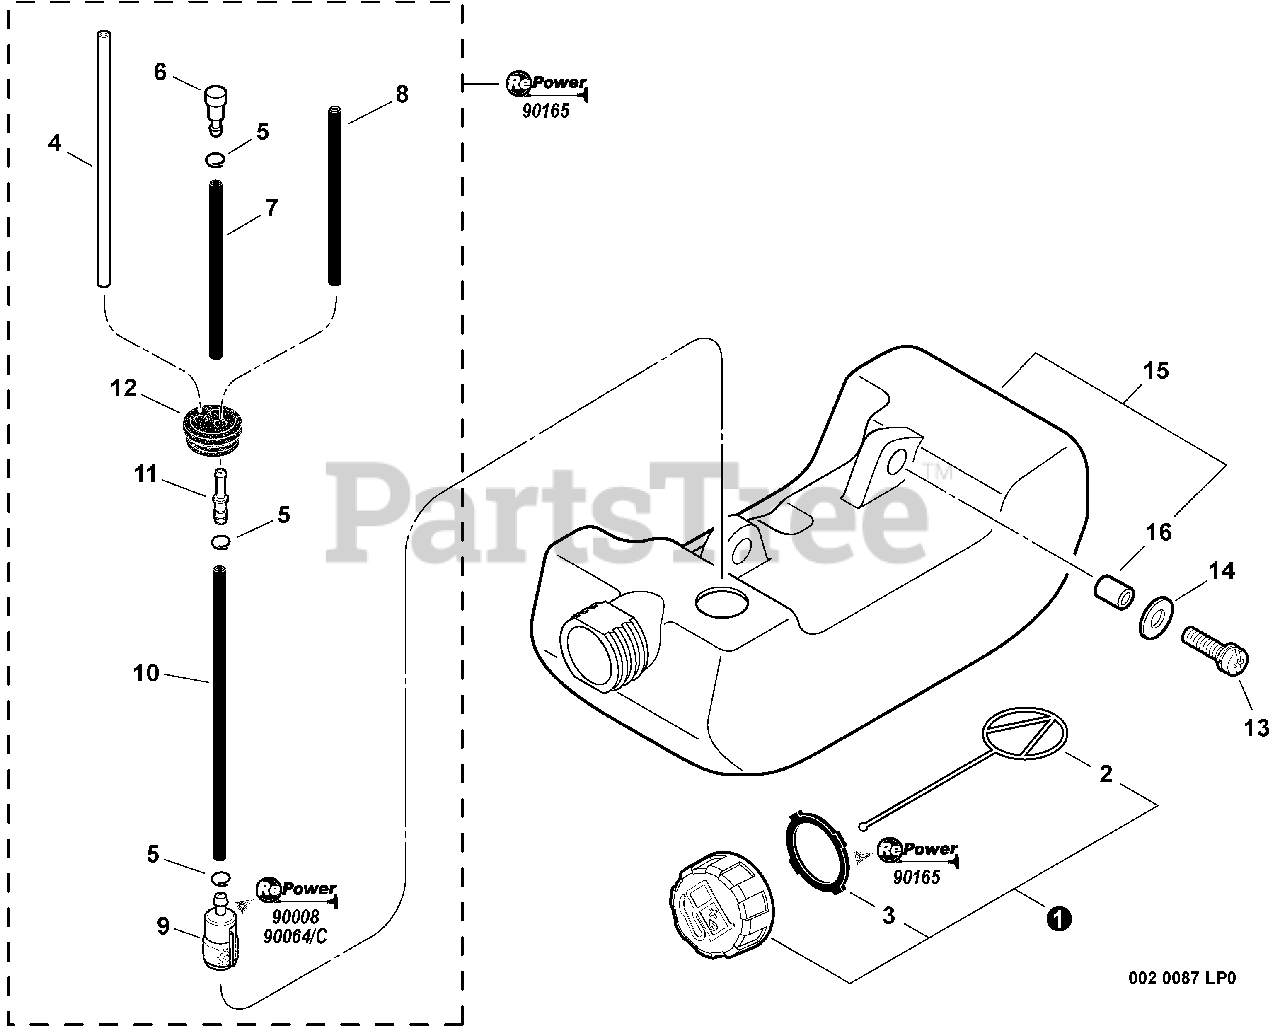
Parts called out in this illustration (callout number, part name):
1	CAP ASSY - ORANGE
2	CONNECTOR, CAP
3	GASKET, CAP
4	PIPE - 3X6X90 -- CLEAR
5	CLIP - 6
6	VENT, FUEL TANK
7	PIPE - 3X5X70 -- BLACK
8	PIPE - 3X5X74 -- BLACK
9	FILTER, FUEL
10	PIPE - 3X5X110 -- BLACK
11	CONNECTOR, PIPE
13	SCREW - 5X16
14	WASHER - 5
15	TANK, FUEL
17	RePower FILTER KIT
18	RePower TUNE-UP KIT
19	RePower FUEL SYSTEM KIT
